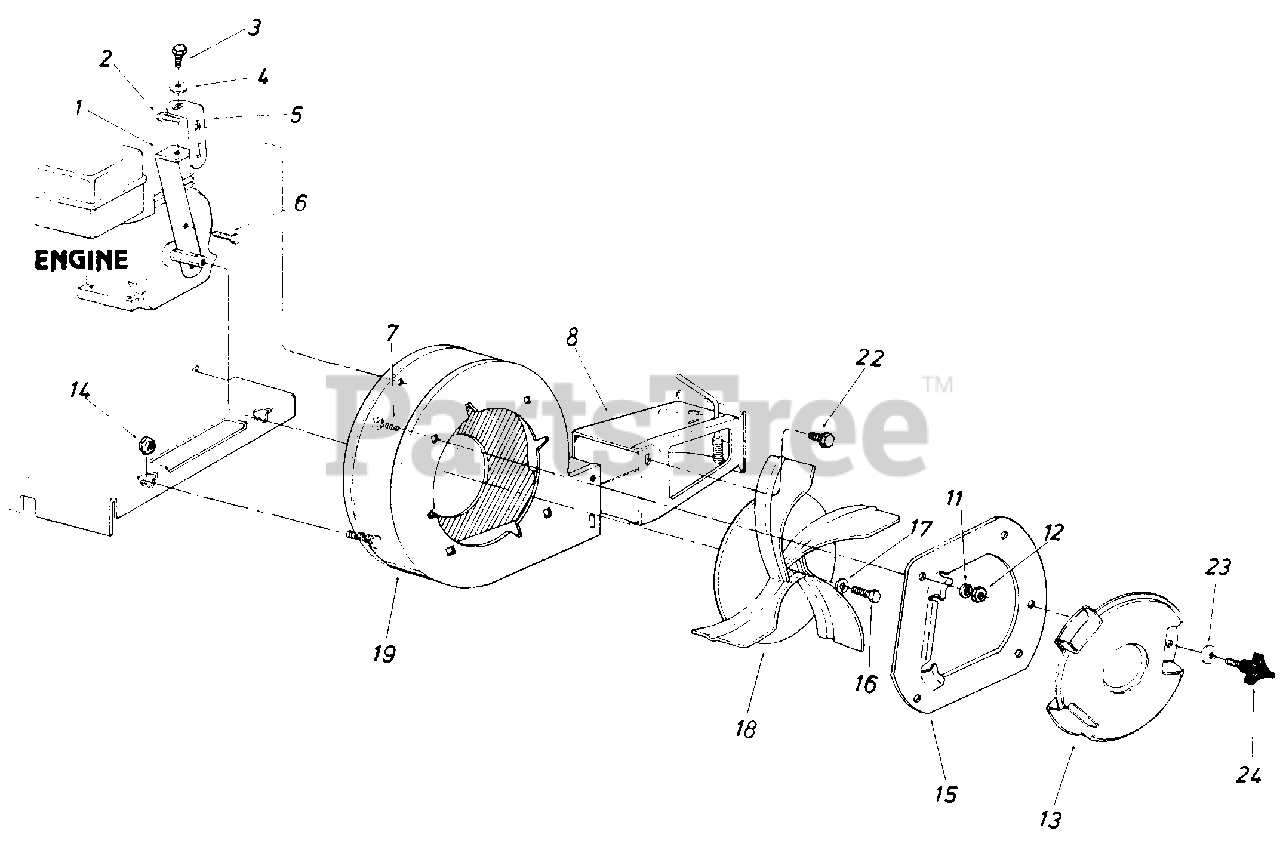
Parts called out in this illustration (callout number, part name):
3	HexBolt5/16-18 x .75" Lg.
4	L.-Wash. 5/16" I.D.
7	Carriage Bolt 5/16-18 x .62" Lg.
12	Hex Nut 5/16-18 Thd.
13	Blower Guard
14	Hex Shoulder Nut .50" I.D.
15	Nozzle Plate Ass'y.
16	Hex Bolt 3/8-24 x 1.25" Lg.
17	L.-Wash. 3/8" I.D. HD.
18	Air Vane Plate Ass'y.
19	Blower Housing Ass'y.-Comp.
22	Hex Sems Bolt 5/16-18 x .62" Lg.
23	Belleville Wash. 34" 1 .D. x .87" 0. D.
24	3-Arm Thumb Scr. 5/16-18 x .75" Lg.
